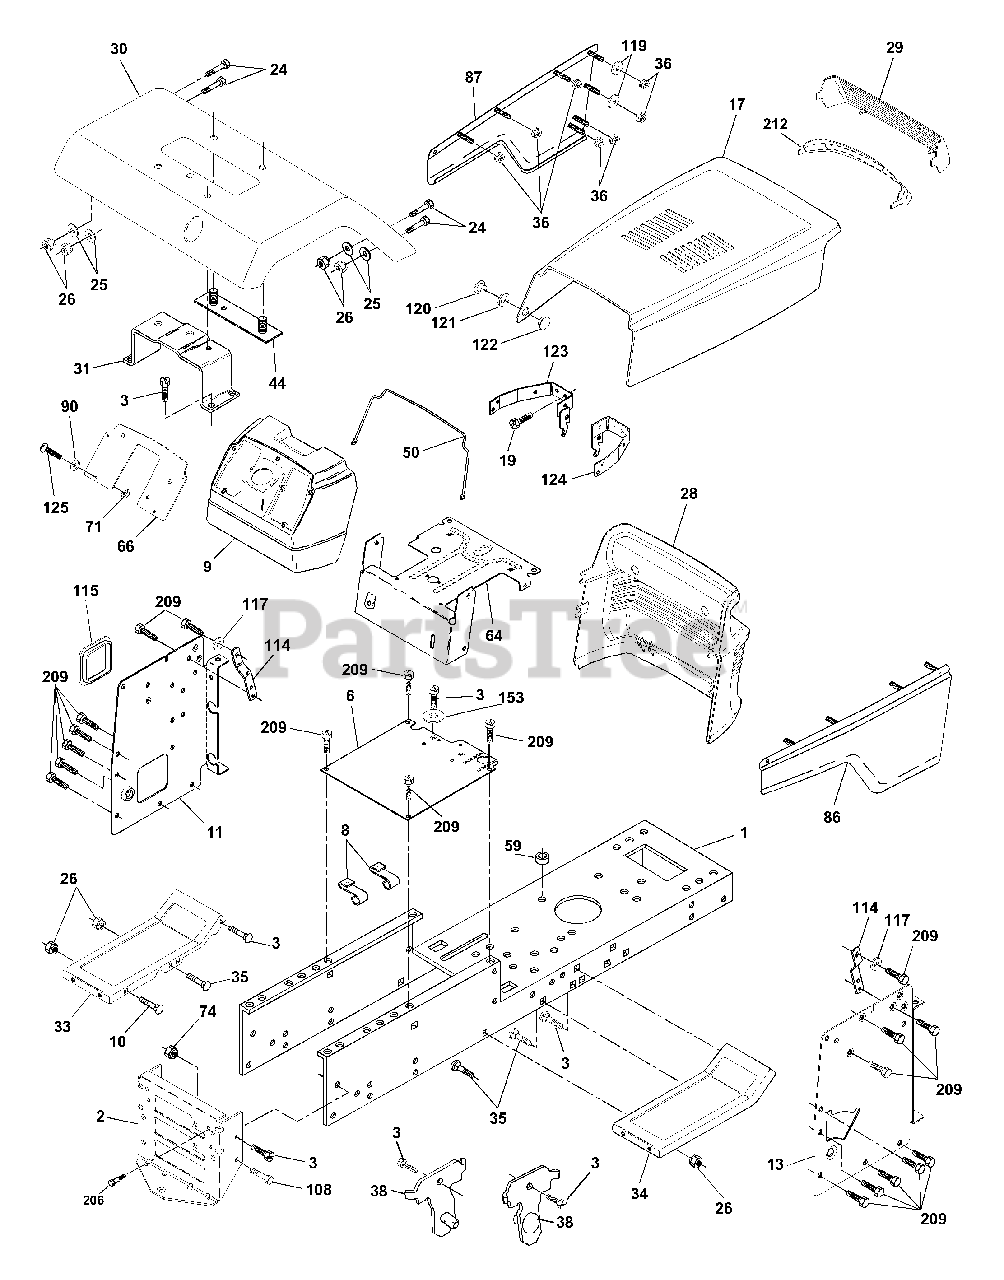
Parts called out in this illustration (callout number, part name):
1	Chassis Wldmt.
2	Drawbar Stretch 94
3	Screw 3/8-16 x 3/4
6	Saddle Flat Lt
8	Clip Insulator
10	Bolt Rd Hd Sqnk. 3/8-16 Unc x 1
11	Panel Dash Lh
13	Panel Dash Rh
19	Screw Hwhd Hi-Lo #13-16 x 3/4
24	Bolt Fin Hex 3/8-16 Unc x 1 Gr. 5
25	Washer 13/32 x 13/16 x 12 Ga.
26	Nut Lock Hex w/Insert 3/8-16 UNC
28	Grill / Lens Asm
29	Lens Grille
30	Fender Asm YTGT
31	Bracket Fender
33	Footrest Pnt. Lh
34	Footrest Pnt. Rh
35	Bolt Rd Hd Sht. Sqnk. 3/8-16 x 3/4
36	Nut Pal
37	Screw Thdrol 5/16-18 x 1/2 Tyt
38	Bracket Asm Pivot Mower Rear
44	Strap Asm Fender
50	Rod Support Hood
59	Bushing Snap Split
64	Dash Lower
66	Plate Dash Slkscr.
71	Nut Keps Hex 1/4-20 Unc
74	Nut Crownlock 3/8-16 Unc
86	Panel Asm. Pnt. Side Rh
87	Panel Asm. Pnt. Side Lh
90	Washer 9/32 x 3/4 x 16 Ga.
108	Bolt Fin Hex 3/8-16 Unc x 3/4
114	Bracket Support Dash
115	Cover Access
117	Washer Serrated Disc 13/32 x 1
119	Washer 9/32 x 1-1/4 x 16 Ga.
120	Rivet Ratchet Female
121	Washer Nylon
122	Rivet Ratchet Male
123	Bracket Asm. Pivot Hood Lh
124	Bracket Asm. Pivot Hood Rh
125	Screw Mach Cr. 1/4-20 x 3/4
153	Washer 13/32 x 1-3/8 x 3 Ga.
206	Bolt Shoulder 5/16-18
209	Screw Hex wsh Thdrol 3/8-16 x 3/4
212	Insert Lens Reflector
